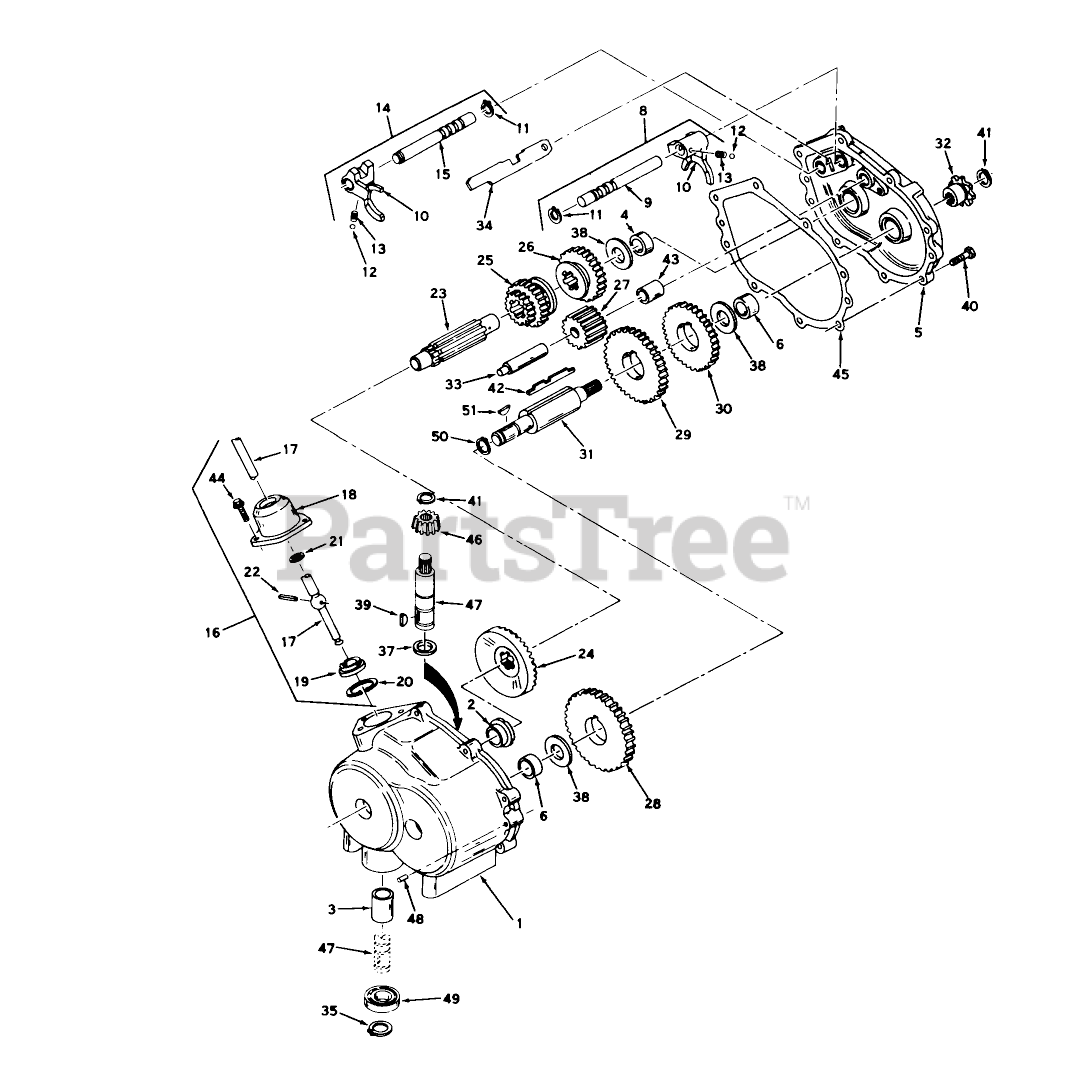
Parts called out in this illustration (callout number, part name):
1	Case Assy., Transmission (Incl. Nos. 2, 3 6)
2	Bearing, Bronze
3	Bearing, Bronze
4	Bearing, Bronze
5	Cover Assembly, Transmission (Incl. Nos. 4 6)
6	Bushing, Bronze
8	Shift Rod Assy (1st and Rev.)(Incl. Nos. 26 thru 30)
9	Shift Rod
10	Shift Fork
11	Ring-Snap
12	Piston ASM
13	Spring
14	Rod Assy., Shift (Incl. Nos. 10 thru 13 15)
15	Rod, Shift
16	Lever Housing Assy., Shift (Incl. Nos. 17 thru 22)
17	Lever, Shift
18	Shift Lever Housing
19	Keeper-Shift Lever
20	Ring-Snap
21	O Ring
22	Roll Pin
23	Shaft, Shifter
24	Gear, Bevel (33 teeth)
25	Gear, Shift 1st 2nd)
26	Gear, Shift 3rd Rev.)
27	Idler, Reverse
28	Gear (39 teeth)
29	Gear (34 teeth)
30	Gear (30 teeth)
31	Shaft, Output
32	Sprocket (8Teeth)
33	Shaft, Reverse Idler
34	Stop, Shifter
35	Ring-Snap
37	Bearing, Thrust
38	Washer
39	Key, Woodruff
40	Screw-Thread Forming
41	Ring-Retainer
42	Key, Countershaft
43	Reverse Idler Spacer
44	Screw
45	Gasket, Transmission
46	Pinion, Input
47	Shaft, Input
48	Dowel Pin
49	Bearing-Ball
50	Snap Ring
51	Kev. Woodruff
